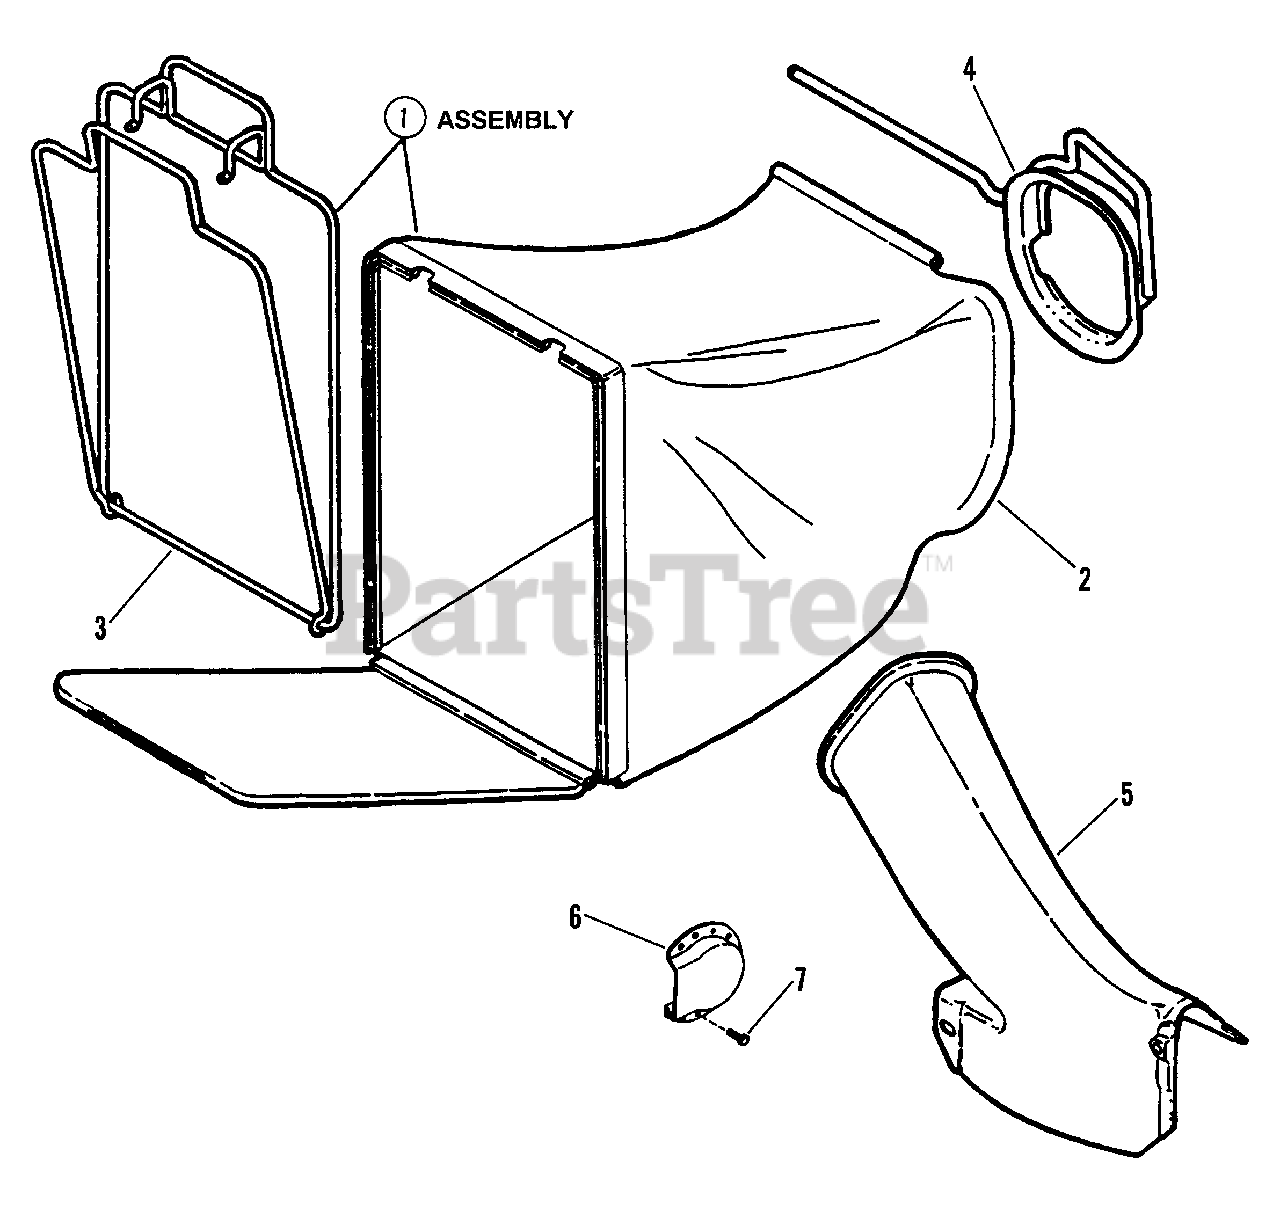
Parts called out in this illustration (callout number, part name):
1	ASSEMBLY, Grass Bag
2	BAG, KWIK-N-EZY
3	ASSEMBLY, Bag Wire
4	CONNECTOR, Grass Bag
5	ADAPTER, Bag
6	DEFLECTOR, Muffler (Briggs)
7	SCREW, #8-18 x 3/8" Hex Head Cap
